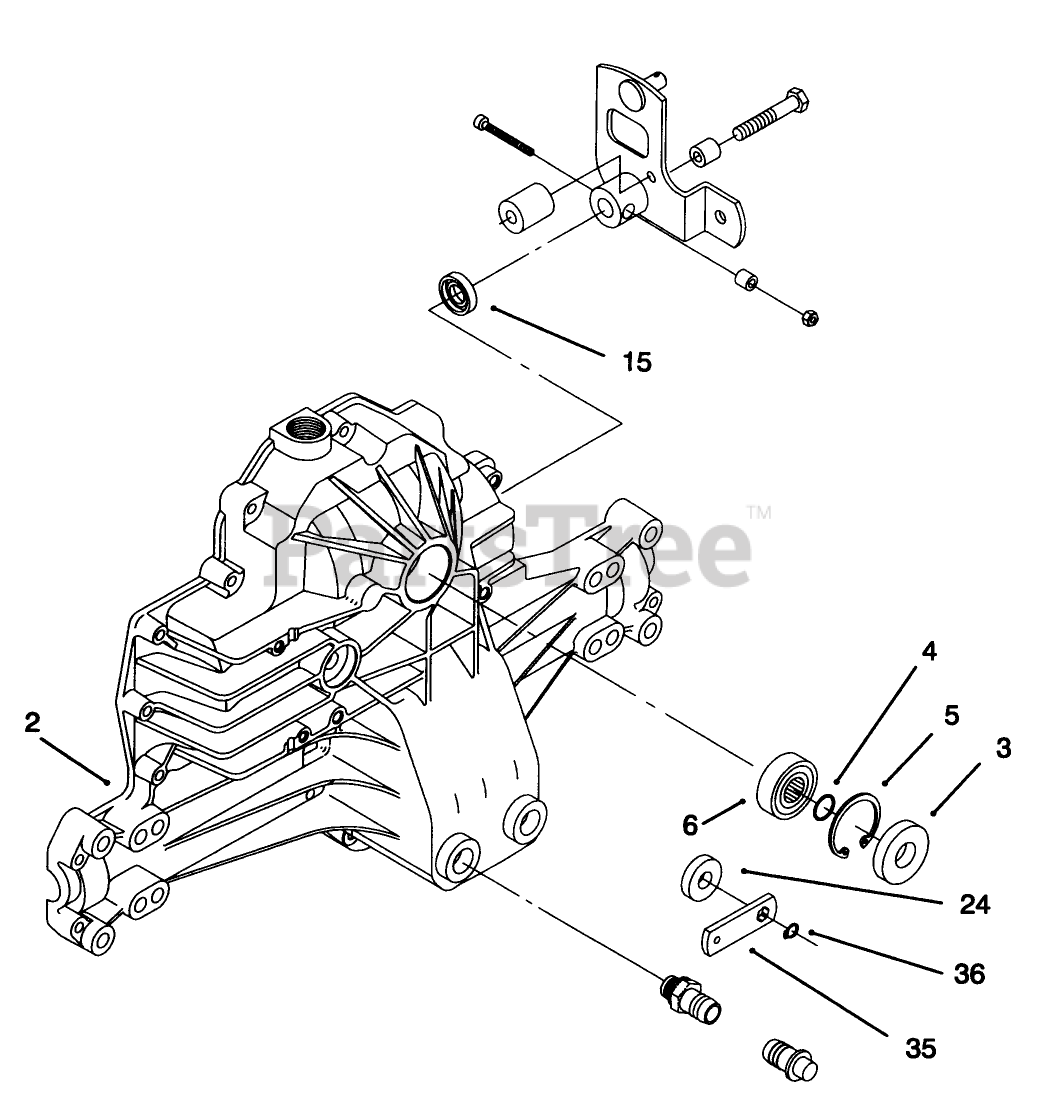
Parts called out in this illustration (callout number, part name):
2	ASM - HOUSING UPPER
3	SEAL-LIP
4	RING-WIRE, RETAINING
5	RING-RETAINING
6	BEARING-SHAFT, BALL
15	SEAL-LIP
24	SEAL-LIP
35	ARM - BYPASS
36	RING-RETAINING
